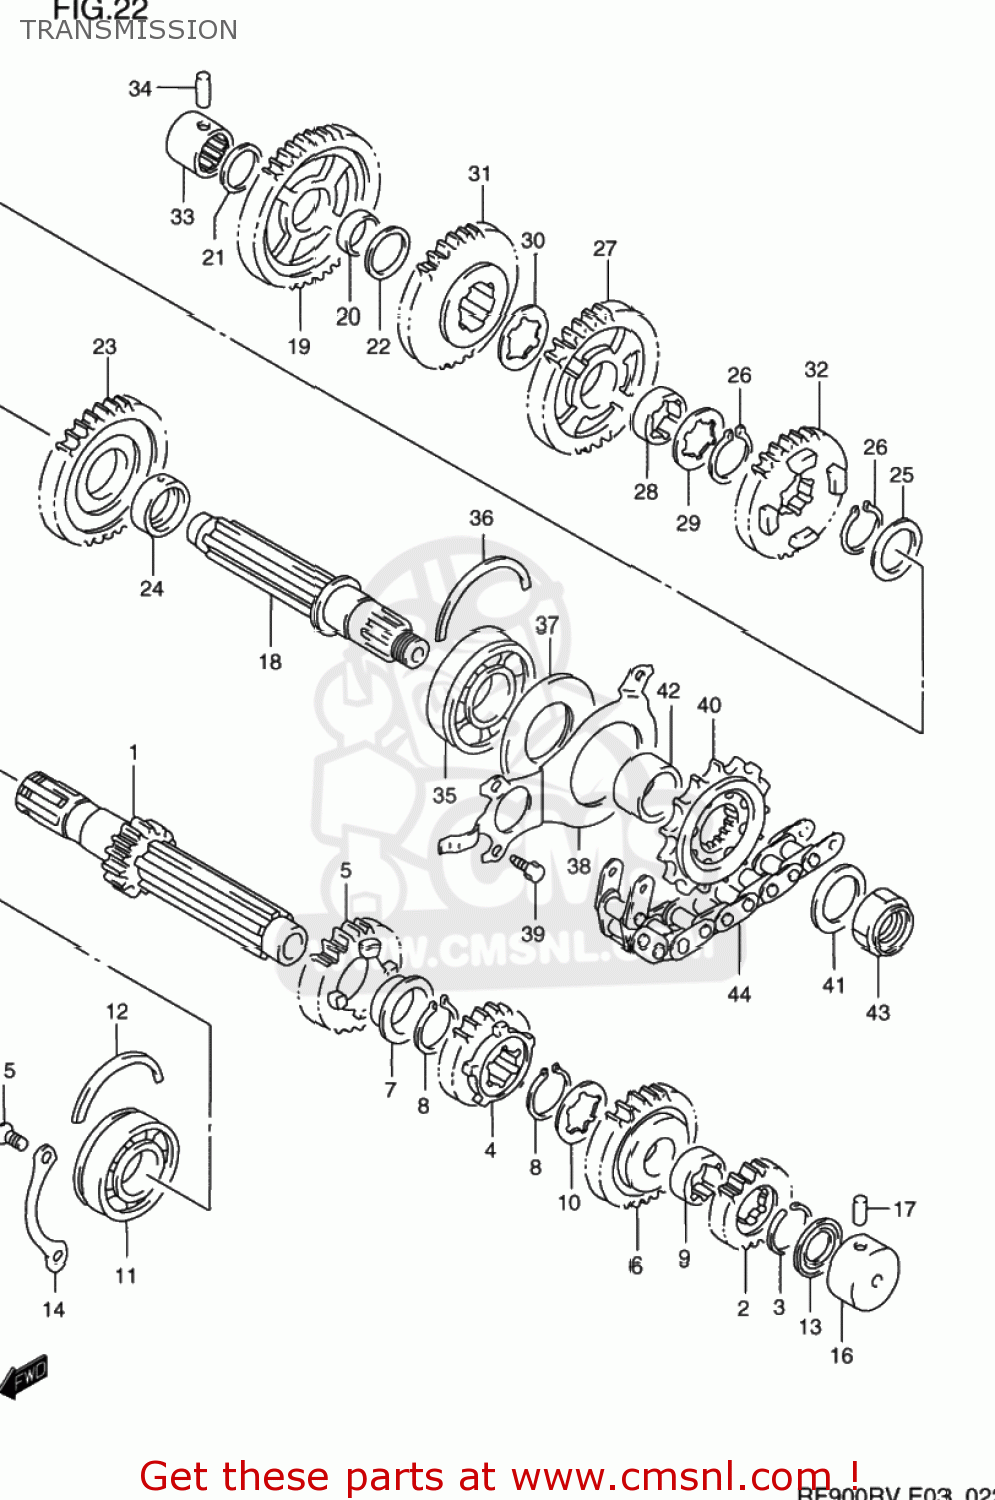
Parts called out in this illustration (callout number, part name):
1	SHAFT,COUNTER
2	GEAR,2ND DRIVE
3	CIRCLIP
4	GEAR,THIRD DRIVE
5	GEAR,FOURTH DRIVE
6	GEAR,FIFTH DRIVE
7	BUSH(28X32X2)
8	CIRCLIP
9	BUSH
10	WASHER,LOCK
11	BEARING(25X62X17)
12	C-RING
13	SEAL,OIL(20X31.2X2.7)
14	RETAINER,CNTR SHAFT BEARING
15	SCREW ,6X16
16	BEARING
17	PIN
18	SHAFT,DRIVE
19	GEAR,1ST DRIVEN
20	BUSHING
21	WASHER
22	WASHER
23	GEAR,2ND DRIVEN
24	BUSH(28X32X11)
25	SHIM(28X38X1)
26	CIRCLIP
27	GEAR,3RD DRIVEN
28	BUSHING,THIRD DRIVEN GEAR
29	WASHER,LOCK
30	WASHER,LOCK
31	GEAR,4TH DRIVEN
32	GEAR,5TH DRIVEN
33	BEARING(20X34X20)
34	PIN
35	BEARING(28X70X18)
36	C RING
37	SEAL,OIL(34.8X70X6)
38	RETAINER,DRIVE SHAFT OIL SEAL
39	BOLT
40	SPROCKET,ENGINE(15T)
41	WASHER,THRUST
42	SPACER(25X36X17.7)
43	NUT
44	CHAIN ASSEMBLY,DRIVE 110LE
